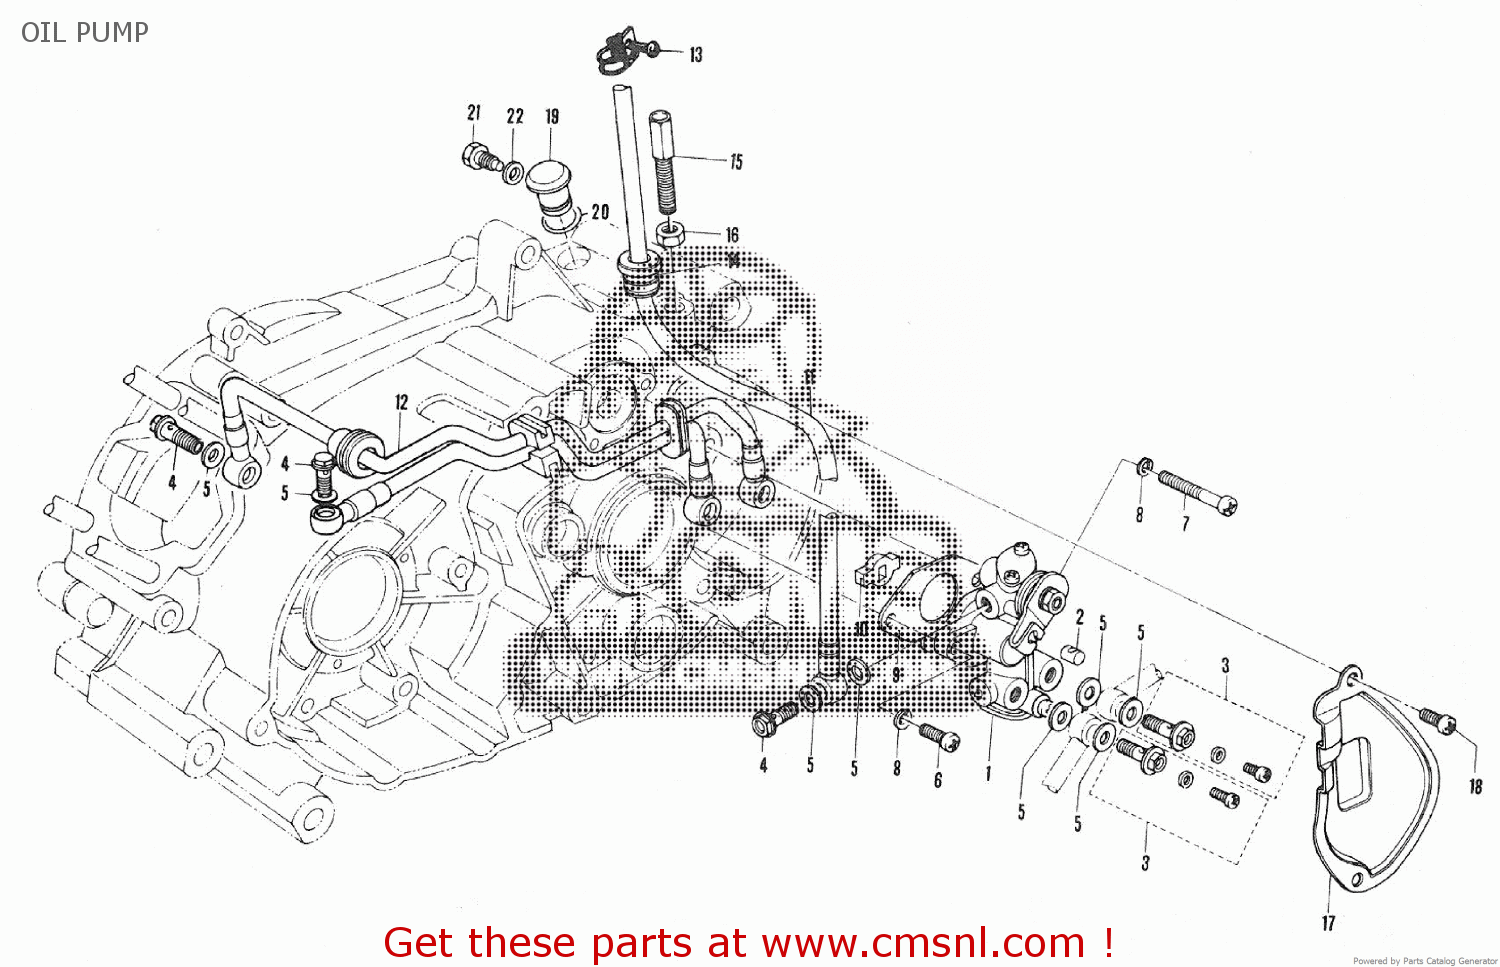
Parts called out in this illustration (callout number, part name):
1	COOLER SET,OIL
2	TERMINAL,CABLE
3	Union Bolt
4	UNION
5	GASKET (NAS)
6	SCREW
7	SCREW
8	LOCK WASHER
9	GASKET,OIL PUMP (MCA)
10	PIECE,OIL PUMP DRIVE
11	HOSE,OIL NO.1
12	HOSE,OIL NO.2
13	CLAMP
14	BUSHING
15	BOLT
16	NUT
17	CAP
18	SCREW, CENTER SHAFT
19	PLUG(OD:19)
20	O RING(D:1.3,ID:9.6)
21	SCREW, CENTER SHAFT
22	WASHER
